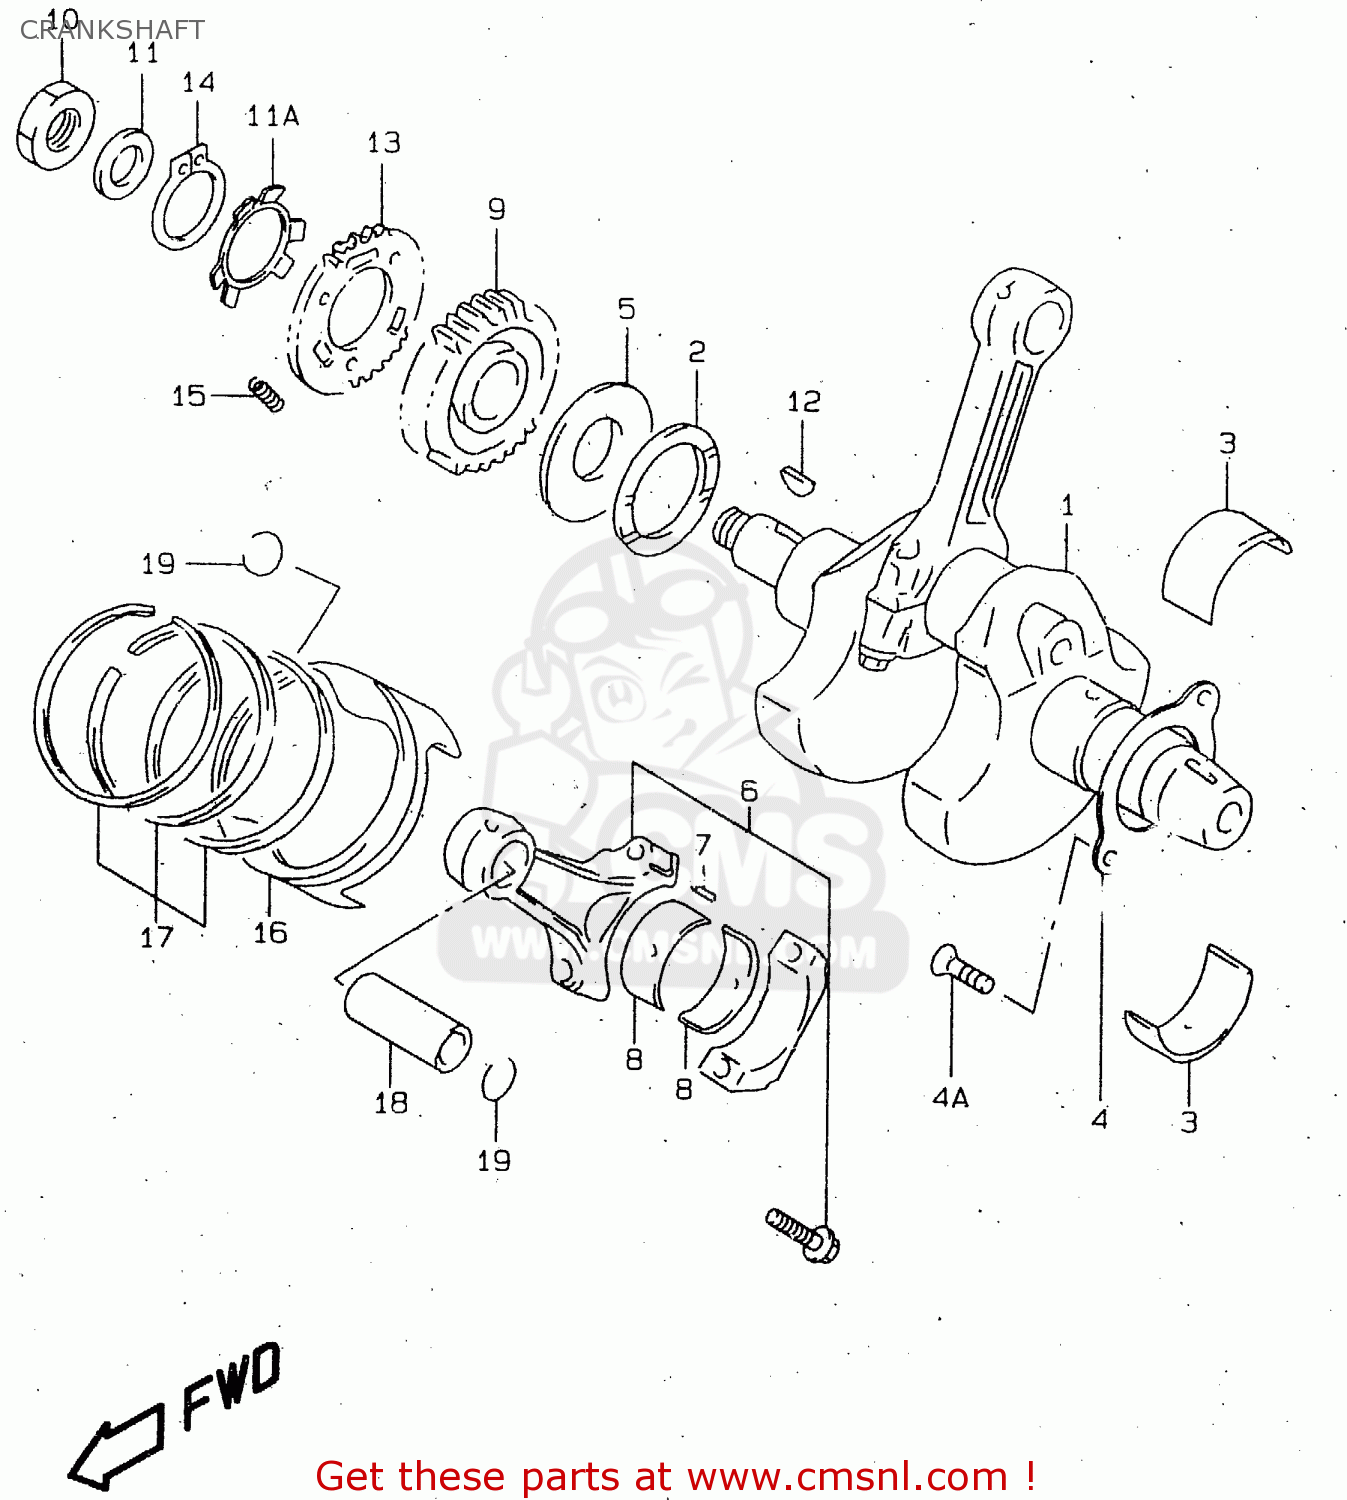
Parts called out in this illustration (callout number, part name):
1	CRANKSHAFT SET
2	WASHER(48.1X64X1.94)
3	BEARING,CRANKSHAFT
4	RETAINER,CRANKSHAFT BAG,L
4A	SCREW(6X12)
5	WASHER,CRANK THRUST
6	CONNECTING ROD ASSY
7	PIN,CONNECTING ROD
8	BEARING,CRANK PIN
9	GEAR,PRIMARY DRIVE
10	NUT
11	WASHER
11A	WASHER,PRI DRIVE
12	KEY
13	GEAR,PRIMARY DRIVE SCISSORS
14	CIRCLIP
15	SPRING
16	PISTON
17	RING SET,PISTON
18	PIN,PISTON
19	CIRCLIP
